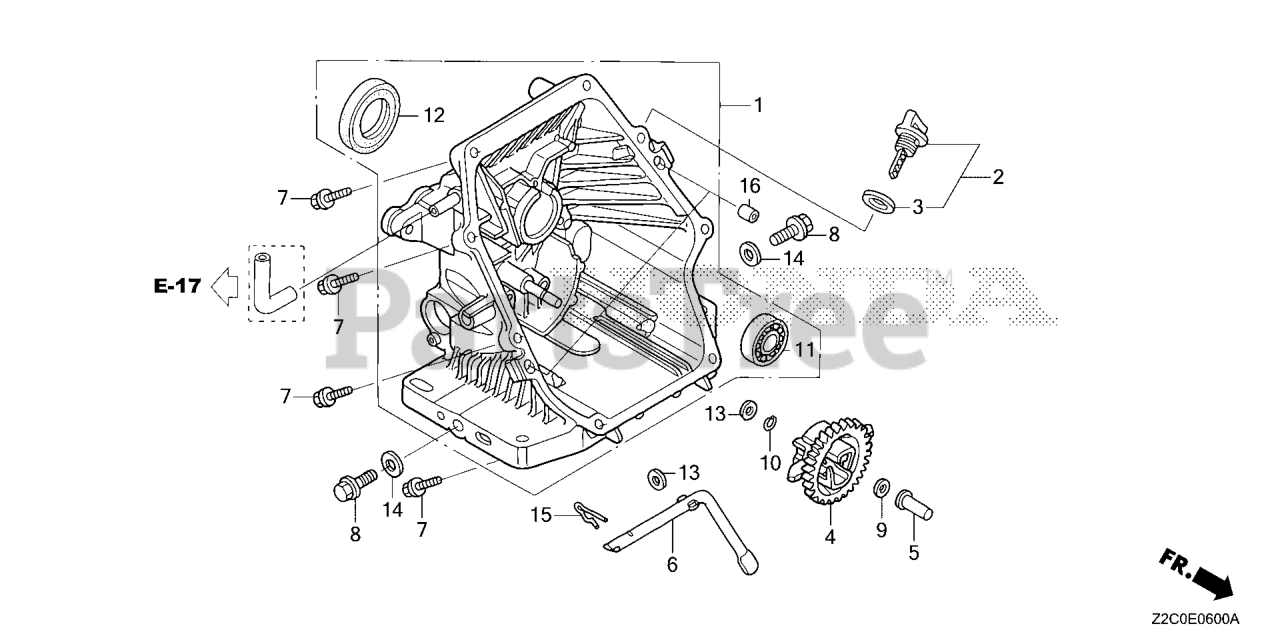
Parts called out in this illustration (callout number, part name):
1	COVER ASSY., CRANKCASE
2	CAP ASSY., OIL FILLER
2	GAUGE ASSY., OIL LEVEL
3	GASKET, OIL FILLER CAP
3	GASKET, OIL FILLER CAP (NOT AVAILABLE)
4	GOVERNOR ASSY.
5	SLIDER, GOVERNOR
6	SHAFT, GOVERNOR ARM
7	BOLT, FLANGE (6X25) Use up to Engine SN 2056819.
8	BOLT, DRAIN PLUG
9	WASHER, THRUST (6MM)
10	CLIP, GOVERNOR HOLDER
11	BEARING, RADIAL BALL (62/28)
12	OIL SEAL (28X41.25X6)
13	WASHER, PLAIN (6MM)
14	WASHER, DRAIN PLUG (12MM)
15	PIN, LOCK (8MM)
16	PIN, DOWEL (8X20)
